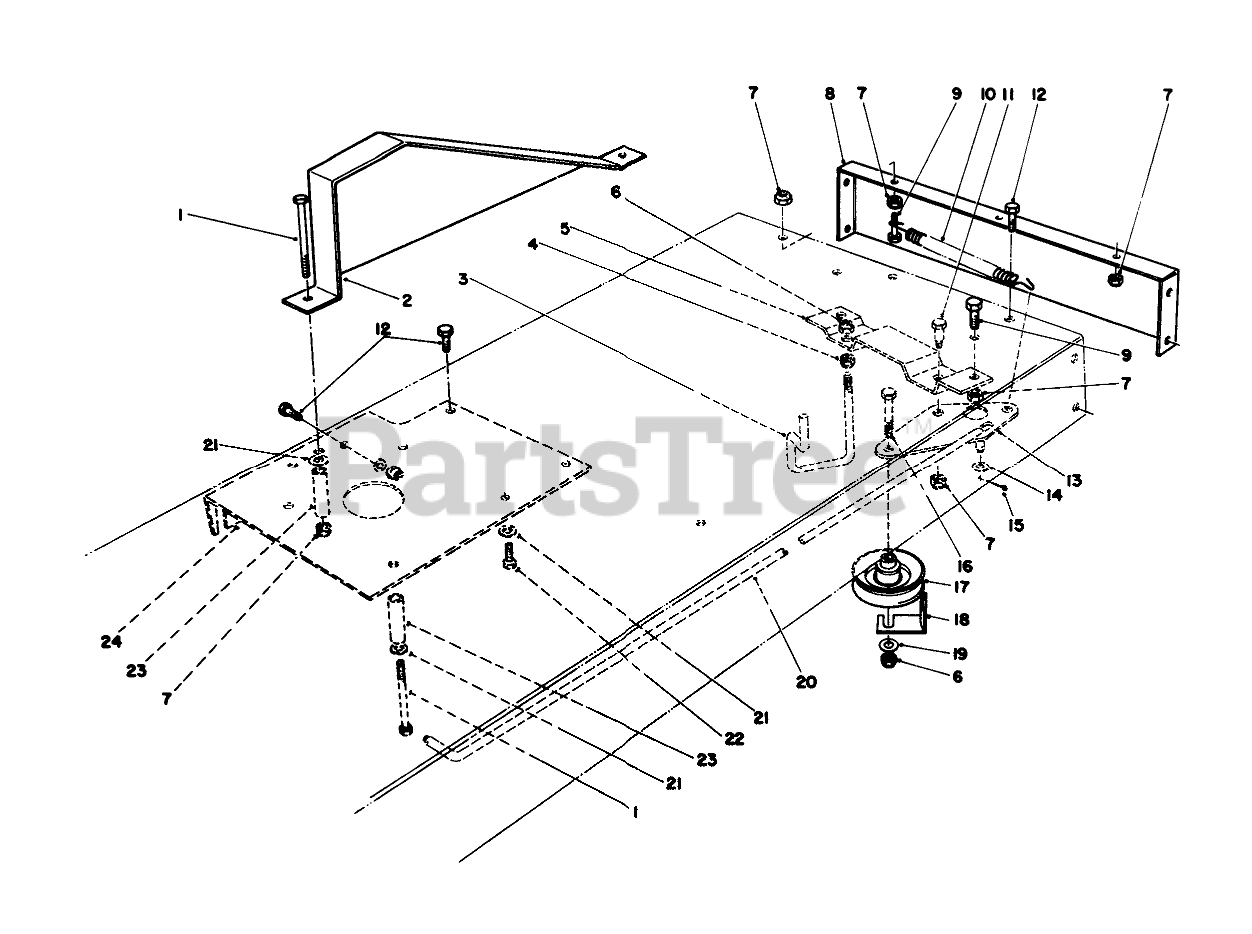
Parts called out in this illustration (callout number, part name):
1	SCREW-HH
2	CHAIN GUARD R
3	BELT GUIDE
4	NUT-LOCK, SIDE
5	TRACT SUPP BRKT B
6	NUT-LOCK, CONE
7	NUT-LOCK, NI
8	REAR FRAME R
9	SCREW-HH
10	TRACTION SPRING
11	BOLT-SHOULDER
12	SCREW-HH
13	TRACTION PIVOT BRKT
14	WASHER-FLAT
15	PIN-COTTER
16	SCREW-HH
17	PULLEY-IDLER
18	RETAINER-BELT
19	WASHER-FLAT
20	TRACTION ROD
21	WASHER-PLAIN
22	Screw-HH
23	OUTER TUBE SPACER
24	REINF PLATE R
